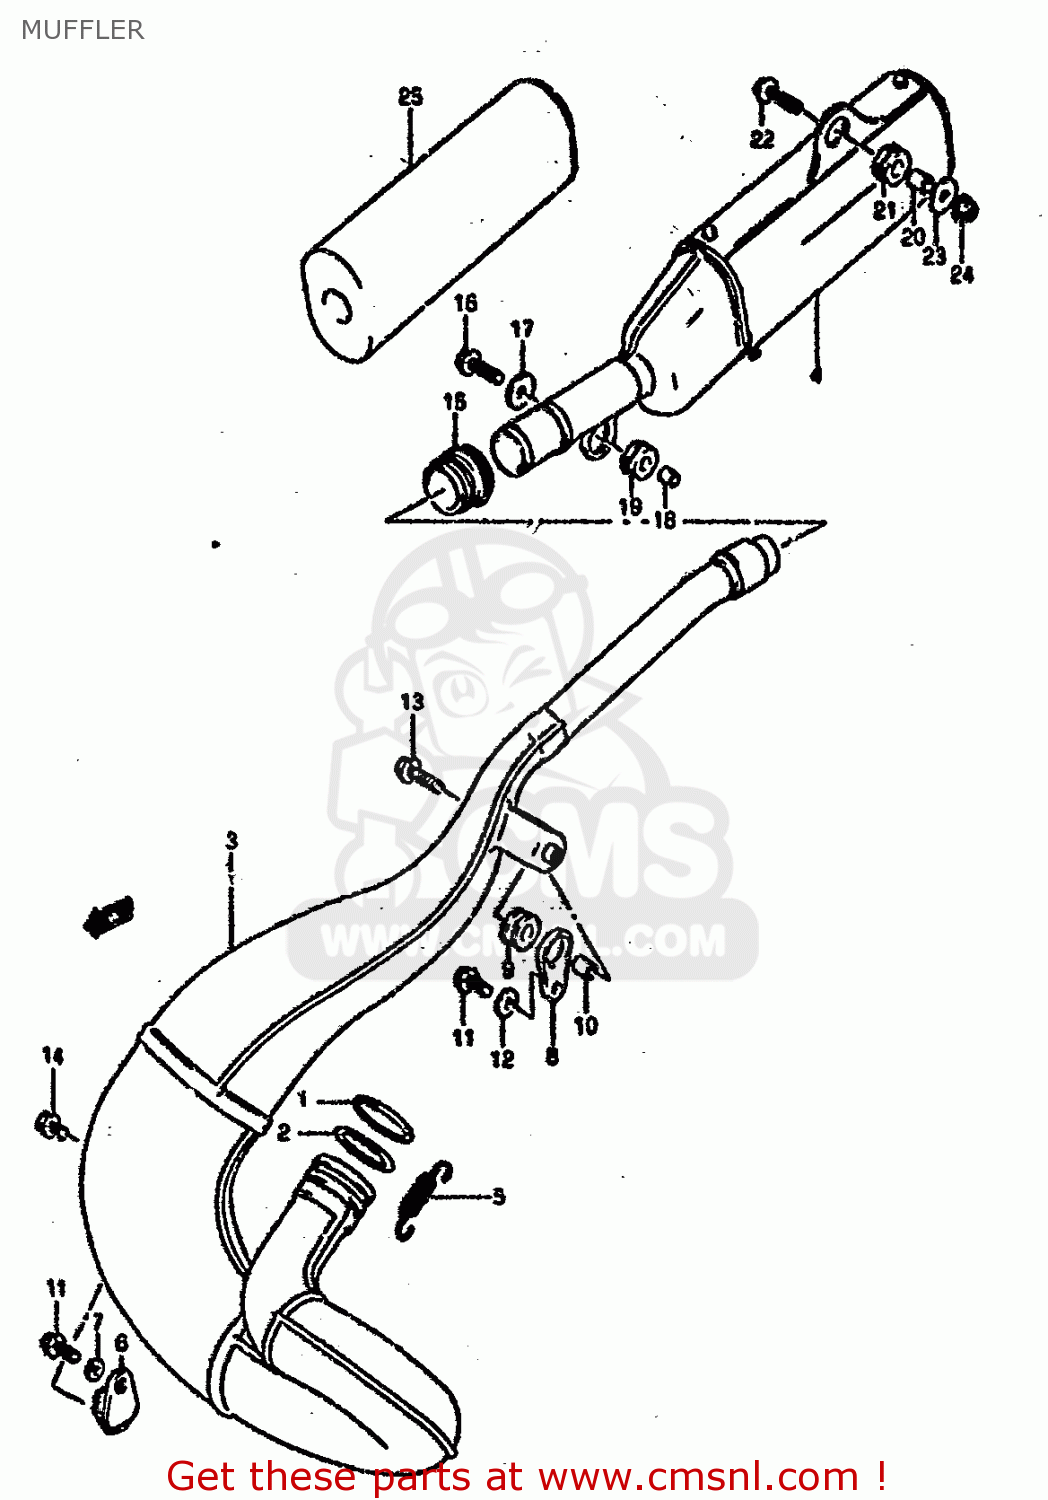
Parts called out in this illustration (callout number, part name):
1	WASHER,EXHAUST PIPE
2	O RING,EXHAUST PIPE
3	BODY,MUFFLER,FIRST
4	BODY,MUFFLER 2ND
5	SPRING
6	DAMPER,MUFFLER SUPPORT
7	WASHER
8	PLATE,MUFFLER MTG
9	CUSHION,MUFFLER
10	SPACER (6.4X9X13.5)
11	BOLT
12	WASHER
13	BOLT
14	BOLT
15	CONNECTOR,MUFFLER
16	BOLT
17	WASHER (6.5X24X1.6)
18	SPACER (6.8X10X9)
19	CUSHION
20	SPACER(6.5X11.5X13)
21	CUSHION
22	BOLT
23	WASHER (6.5X24X1.2)
24	NUT
25	SILENCER,MUFFLER
